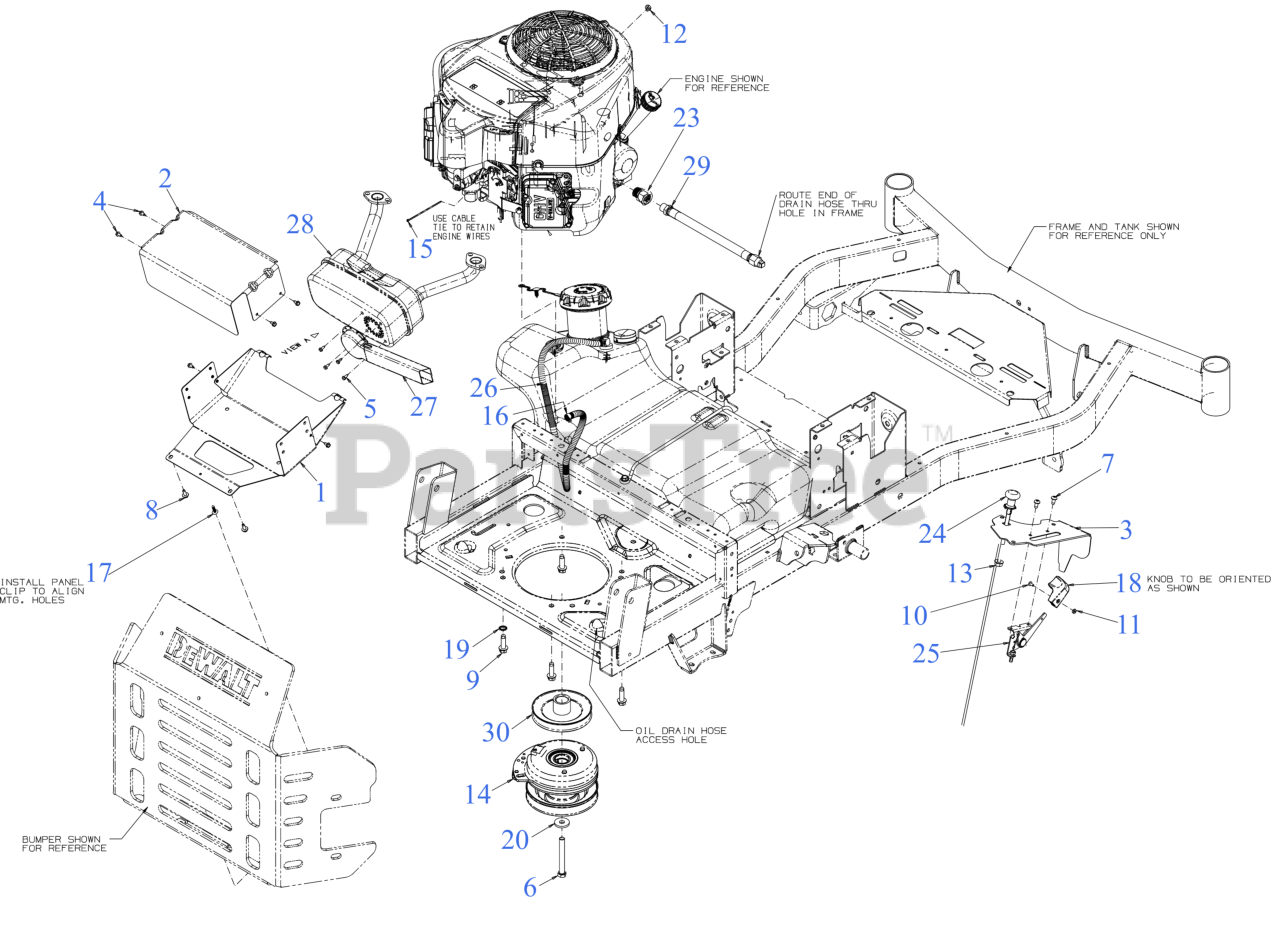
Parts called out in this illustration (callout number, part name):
1	MUFFLER SHIELD (LOWER)
2	MUFFLER SHIELD (TOP)
3	THROTTLE COVER PLATE
4	HEX SCREW AB-TAP #10 x .50
5	HEX SCREW WASHER HD #8-18 x 0.500
5	SCREW 7/16-20 x 3.5 GR5
7	SCREW 1/4-20 x .5
8	SCREW M6-1 x .625
9	SCREW 3/8-16 X1.250
10	SCREW #8-32X.38 LG
11	HEX NUT 8-32
12	HEX NUT 1/4-20
13	HEX FLANGE NUT
14	ELECTRIC PTO CLUTCH
15	CABLE TIE
16	HOSE CLAMP 1/20
17	RATCHET CLIP (.188 x .85)
18	THROTTLE CONTROL KNOB
19	LOCK WASHER 3/8
20	FLAT WASHER .445 x 1.248 x .170
23	OIL DRAIN FITTING (M20x2.5)
24	CHOKE CABLE 40.5 LG
25	THROTTLE CABLE 38.5"
26	FUEL HOSE LOW PERMEATION 28"
27	MUFFLER DEFLECTOR
28	EXHAUST MUFFLER
29	OIL DRAIN HOSE (11.26" 3/8 NPT)
30	TRANSMISSION DRIVE PULLEY
